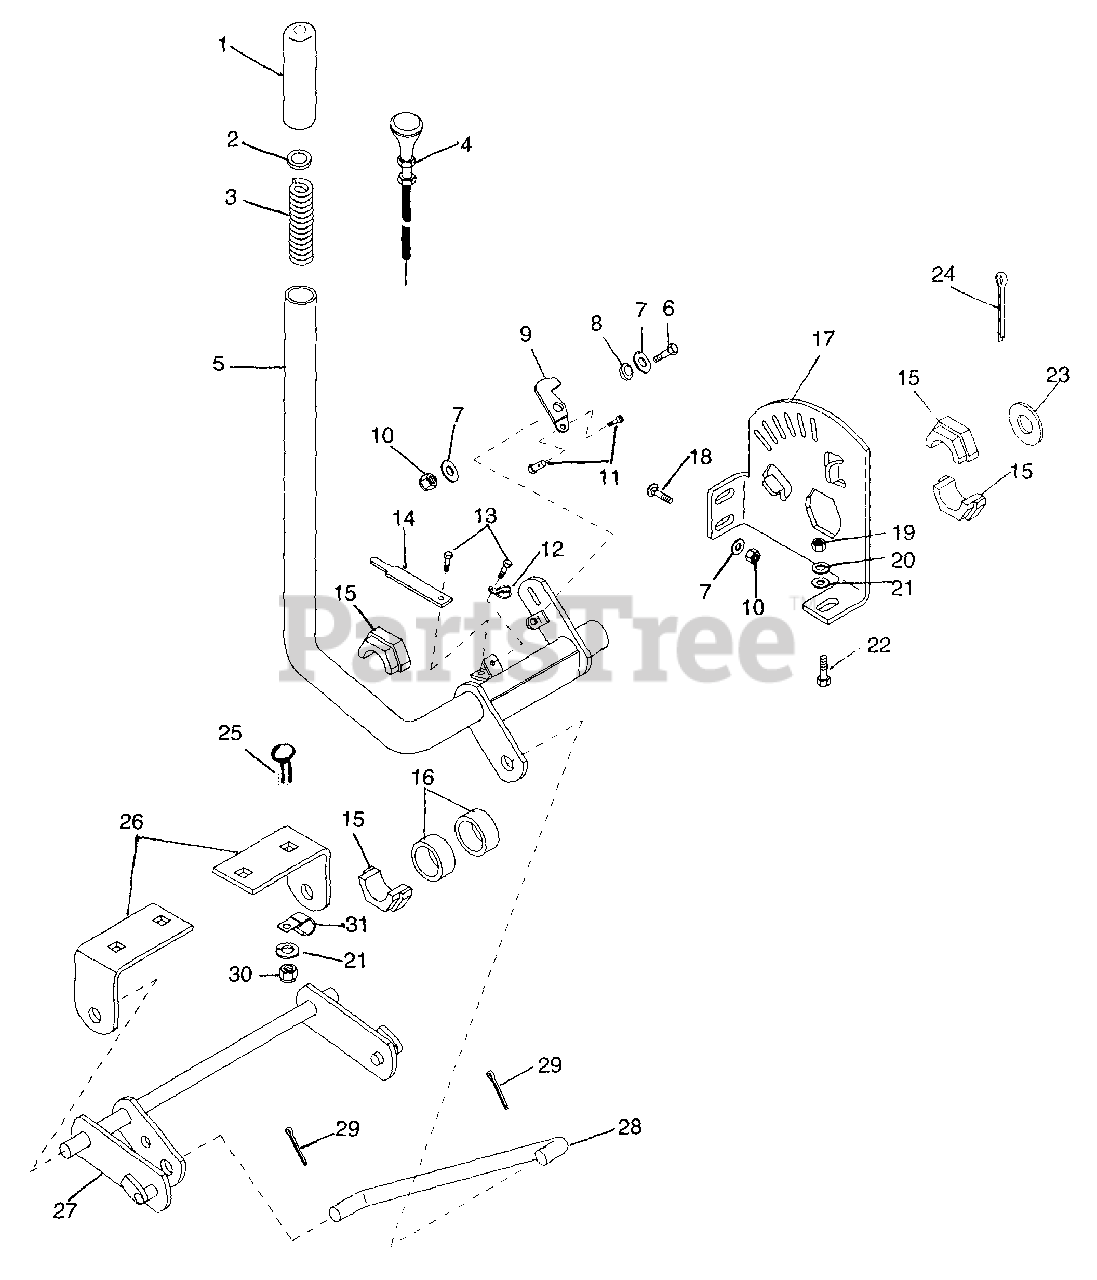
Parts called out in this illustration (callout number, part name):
1	HANDLE GRIP
2	WSHR-FL-STL.312X.734X.065PL
3	SG-COMP .048X.59X2.06 WLD9
4	PUSH-PULL CONTROL
5	LIFT LEVER
6	BLT-HEX .31-18X.75 PL GR5
7	WSHR-FL-STL.312X.734X.065PL
8	SPACER BUSHING .5 X .32 X .21
10	NUT-LK .312-18 GR A PL
11	SWIVEL ASSY
12	CABLE CLAMP NON SKID
13	SCR-TAP 10-16X.50 HWH PL AB
14	INDICATOR
15	BSHG-FLG 1.014X1.750X.72
16	SPACER 1.070X1.380X.615
17	QUADRANT
18	BLT-RDHDSQNK .312-18X.62 PL
19	NUT-LK-CTR .375-16 GR A PL
20	WSHR-FL-STL.406X.812X.065PL
21	WSHR-LK .375X.094 MED PL
22	BLT-HEX .38-16X1.00 PL
23	WSHR-FL-STL 1.016X1.625X.045
24	PIN-COTR .25X1.50 ST PL
25	BLT-RDHDSQSHNK .38-16X1.00 PL
26	CENTER LIFT BRACKET
27	CENTER LIFT LEVER
28	LIFT LINK
29	PIN-COTR .12X1.0 PL
30	NUT-HEX .375-16
31	J-CLAMP
